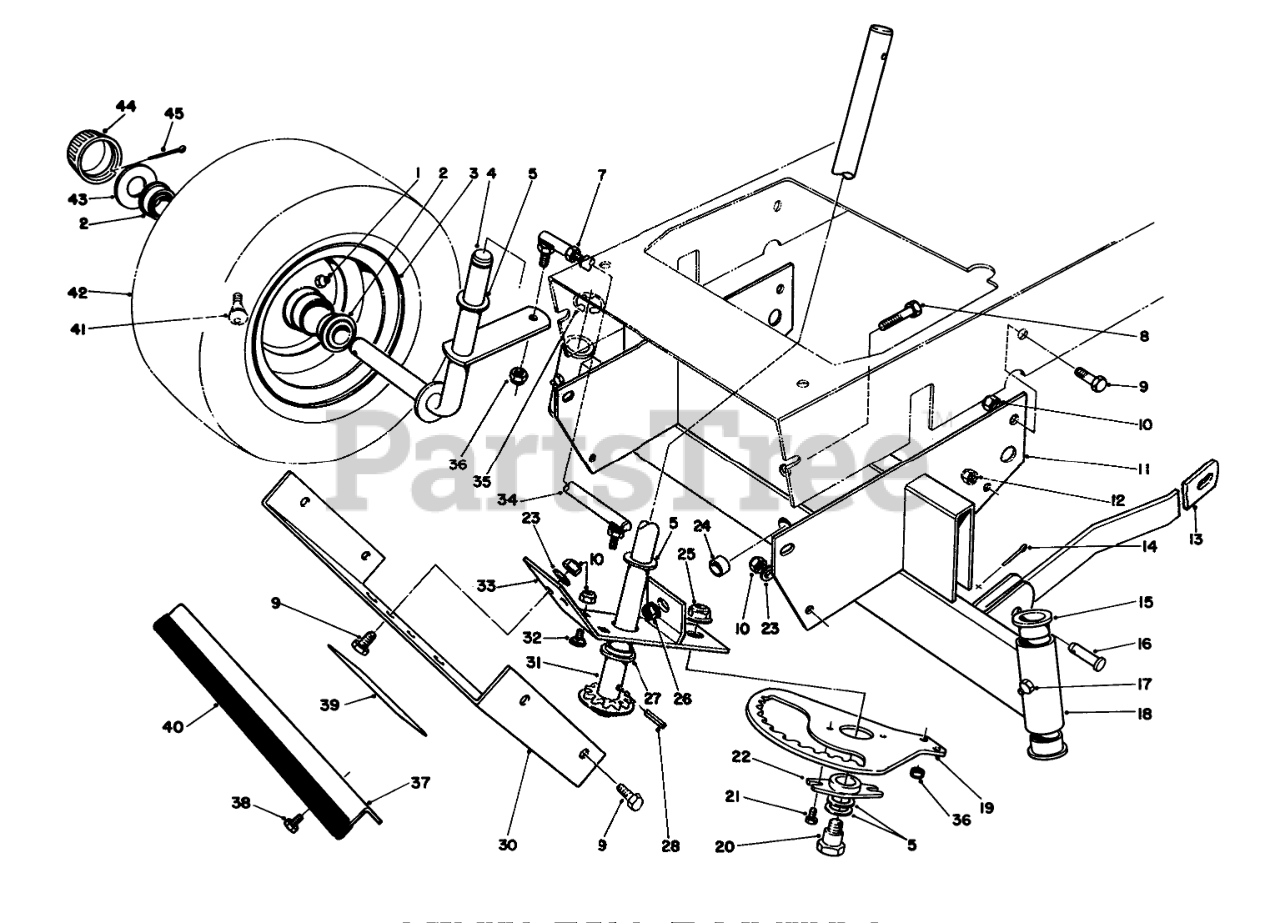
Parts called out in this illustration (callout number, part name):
1	FITTING-GREASE
2	Bearing
4	Spindle RH
5	WASHER-THRUST
7	NUT-JAM
8	SCREW-HH
9	SCREW-HH
10	NUT-LOCK, NI
11	Support
12	NUT-HEX
13	Arm-Suspension, Front
14	PIN-COTTER
15	BEARING-FLANGE
16	PIN-CLEVIS
17	GREASE FITTING
18	Axle-Front (Incl. Ref. #15 & 17)
19	Rack-Steering
21	SCREW-HWH
22	BUSHING-SECTOR
23	WASHER-PLAIN
24	SPACER-AXLE, FRONT
25	NUT-HF
26	NUT-HF
27	BEARING-FLANGE
28	PIN-ROLL, SLOTTED
30	Cover-Front
31	STRG SHAFT WA
32	SCREW-CARR
33	Bracket-Rack, Steering (Incl. Ref. #27)
34	Tie Rod-Adjustable (Incl. Ref. #7)
35	E-RING
36	NUT-LOCK
37	FRONT GUARD R
38	SCREW-HWHTF
39	Decal-Warning
40	TRIM-FRONT GUARD
41	Stem-Valve
42	TIRE,PNEU.11X4.00X5
43	WASHER-PLAIN
44	CAP-HUB
45	PIN-COTTER
